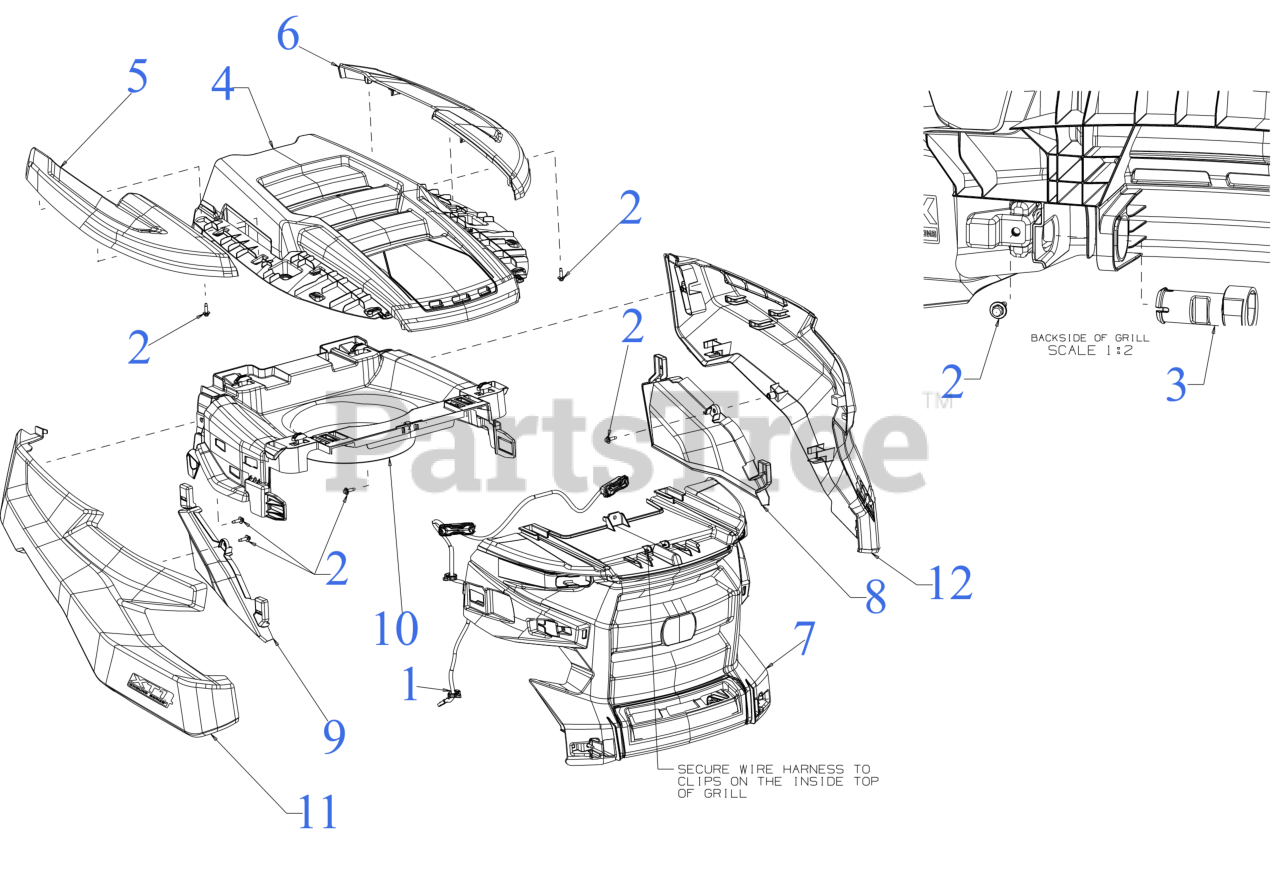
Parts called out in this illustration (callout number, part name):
1	HEADLIGHT HARNESS (W/LED)
2	SCREW 1/4-10 x .750
3	HOOD PIVOT PIN
4	HOOD (TOP)
5	HOOD (TOP) (RH)
6	HOOD (TOP) (LH)
7	GRILLE (FRONT) (T STYLE)
8	PANEL (LOWER SIDE) (LH)
9	PANEL (LOWER SIDE) (RH)
10	PLENUM/HOOD FRAME
11	PANEL (UPPER) (RH) (T STYLE)
12	PANEL (UPPER) (LH) (T STYLE)
